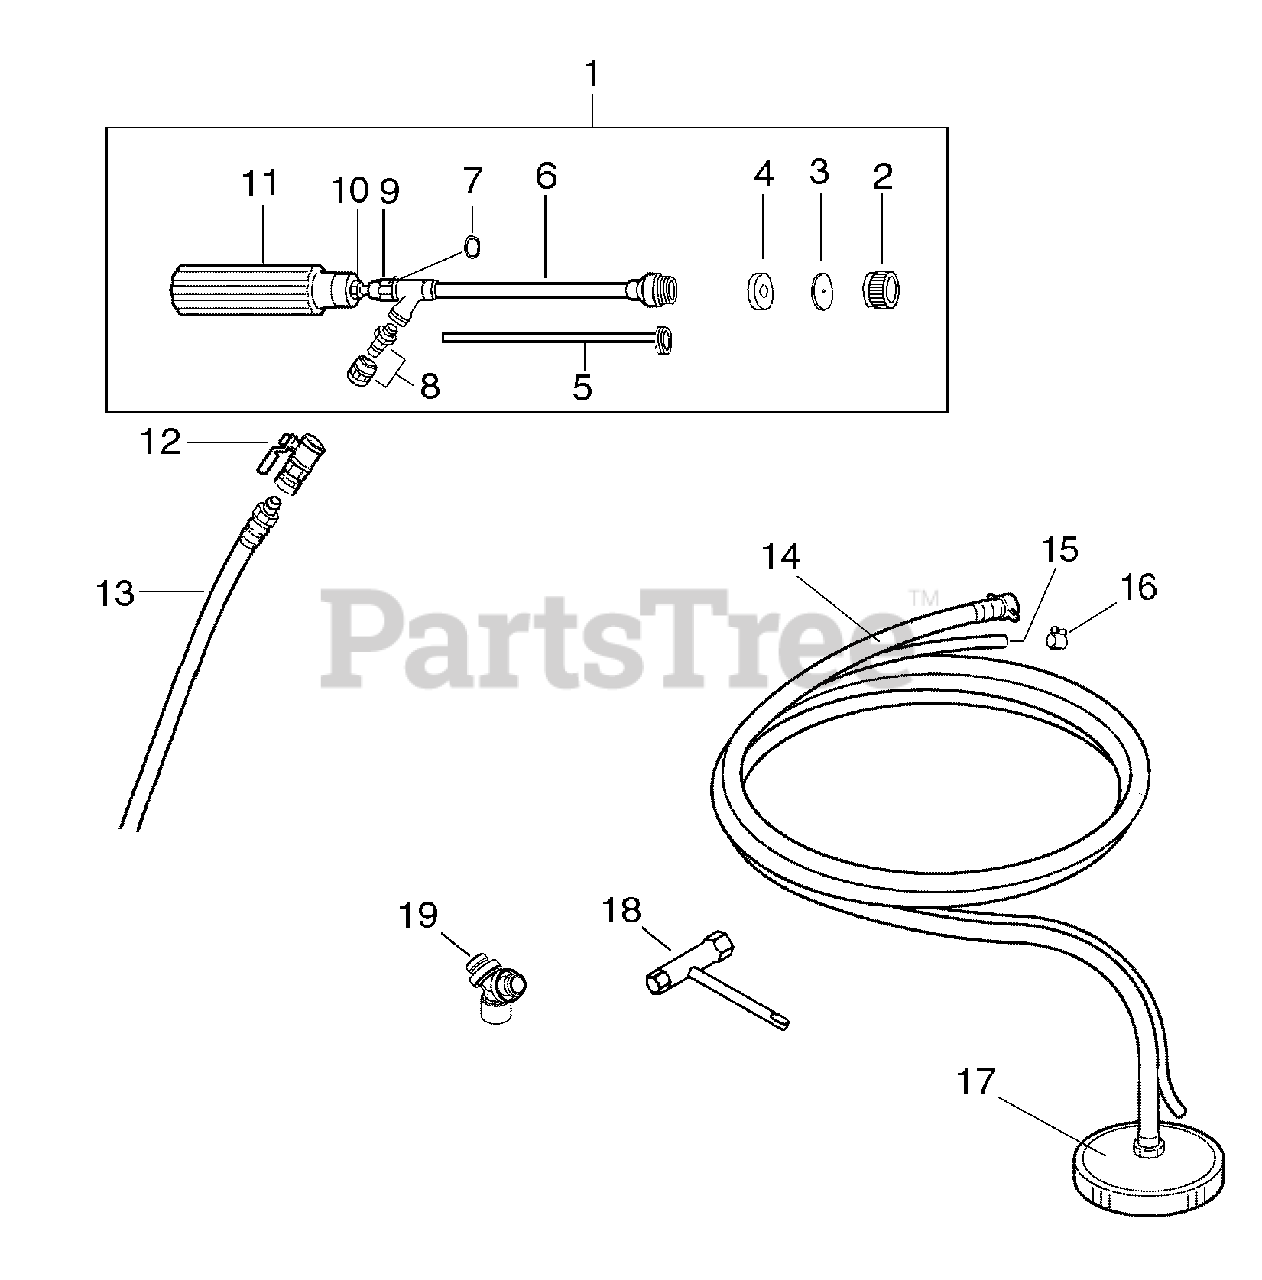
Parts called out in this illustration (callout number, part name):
1	Nozzle,Unit
3	Disk Nozzle
4	Packing Pipe
5	Nozzle Adjuster
6	Pipe Nozzle
8	Hose Coupling
9	Nut Cap
10	Nut Lock
11	Grip Nozzle
12	Cock,Liquid
13	Hose,Liquid
14	Hose,10
17	Strainer
18	Wrench, W/S. Driver
19	Y,Hose 1/4
